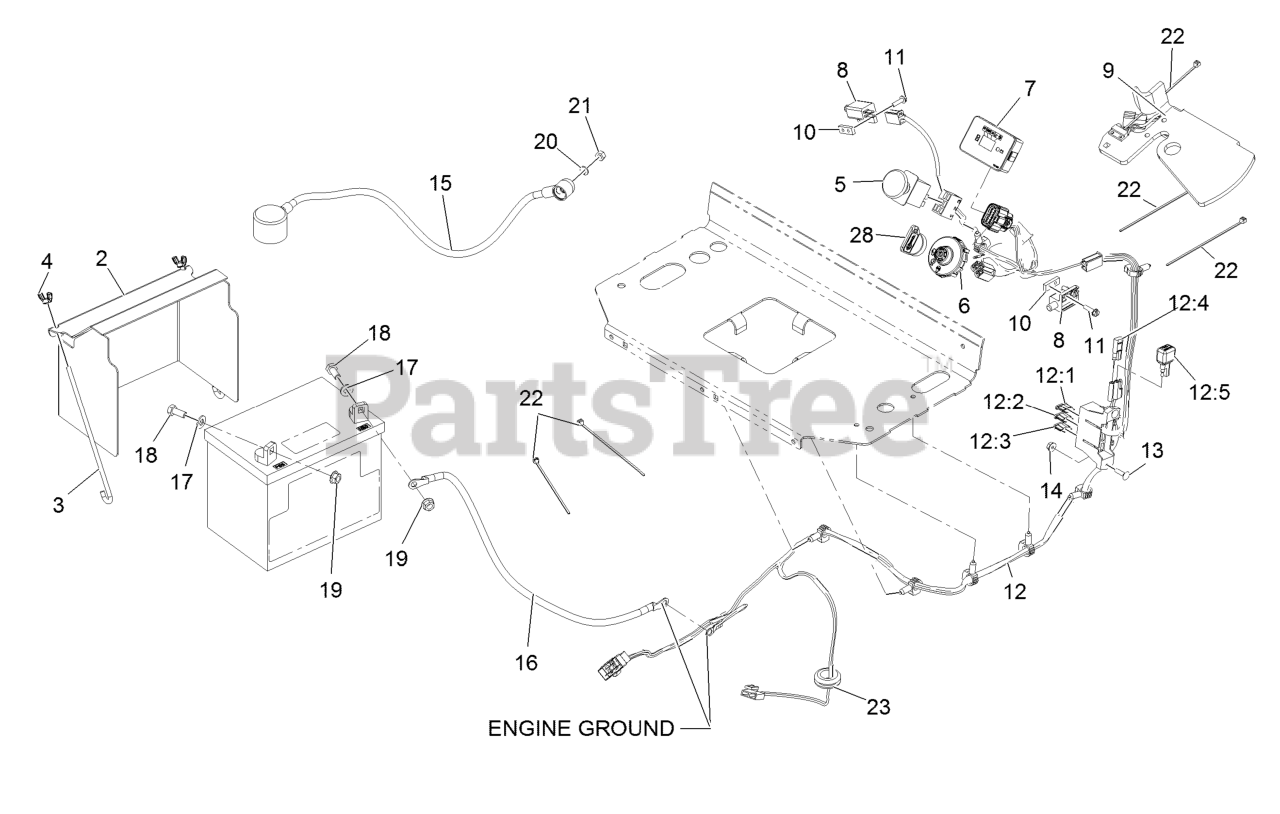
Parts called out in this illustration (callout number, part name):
2	COVER-BATTERY
3	BOLT-HOLDDOWN
4	WINGNUT
5	SWITCH-PTO, ON-ON
7	MODULE-HOUR METER
8	SWITCH-CLOSED, NORMALLY
9	HARNESS-SWITCH, REED
10	PLATE-TAPPED
11	SCREW-HWH
12	HARNESS-WIRE
12:1	FUSE-BLADE, 30 AMP
12:2	FUSE-BLADE, 25 AMP
12:3	FUSE-BLADE, 10 AMP
12:4	CAP-PLUG
13	SCREW-CARR
15	CABLE-BATTERY, POSITIVE
16	CABLE-BATTERY, BLACK
17	WASHER-PLAIN
18	SCREW-HH
19	NUT-HHF, SMOOTH
20	SCREW-HH
21	NUT-HEX
22	TIE-CABLE
23	GROMMET
28	KEY-IGNITION
